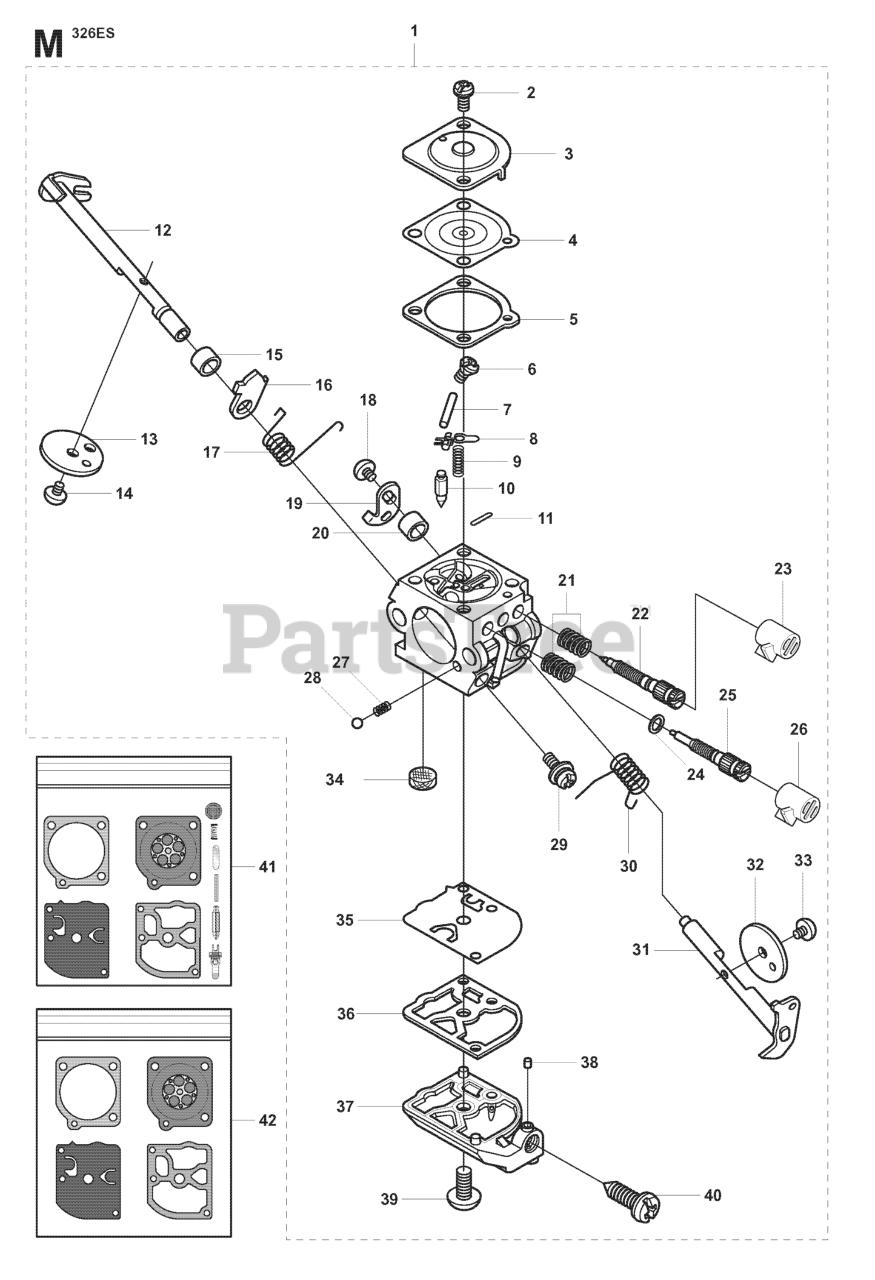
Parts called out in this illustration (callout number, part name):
1	CARBURETOR
7	PIN RETAINING SCREW
9	SPRING
10	INLET NEEDLE
21	SPRING
22	LOW SPEED NEEDLE
26	NEEDLE HIGH SPEED
30	SPRING THROTTLE
32	THROTTLE FLAP
35	PUMP DIAPHRAGM
41	GASKET KIT (ZAMA GND39)
42	CARBURETOR KIT (ZAMA RB69)
